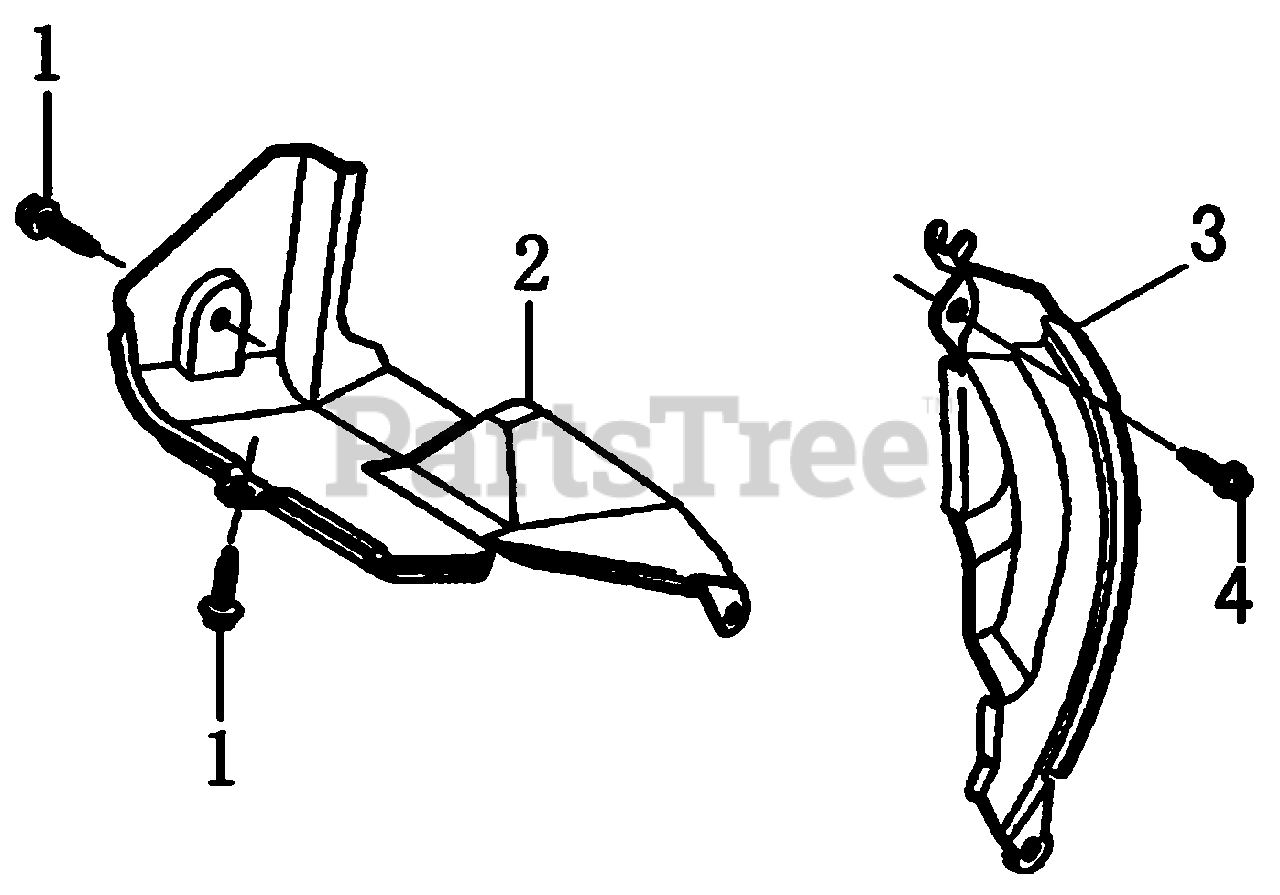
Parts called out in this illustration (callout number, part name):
1	BOLT, FLANGE 6x8
2	SHROUD COMP
3	PLATE, SIDE
4	BOLT, FLANGE, 6x20
